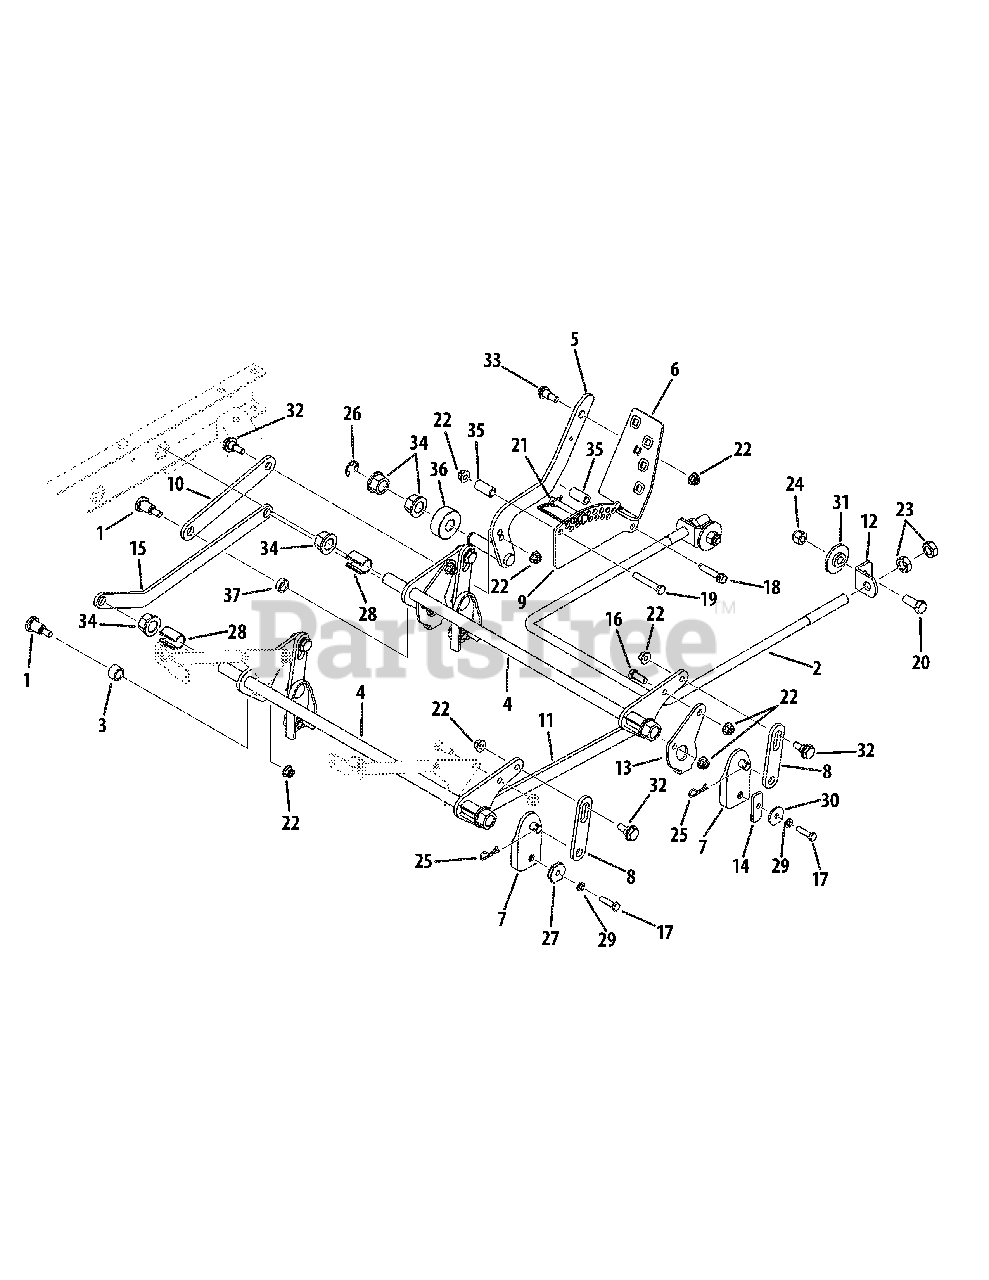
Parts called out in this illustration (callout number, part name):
1	Shoulder Screw, .625 x .830
3	Spacer, .632 x .877 x .548
5	Foot Lift Pivot Assembly
6	Lift Pedal Assembly
6	Lift Pedal Service Kit
6	Torsion Spring
6	Screw .50X.925
7	Deck Lift Adjustment Bracket
12	Front Hanger Rod Bracket Mount
13	Deck Up Stop Bracket
14	Deck Lift Square Spacer
15	Mid-Angled Link Plate
16	Hex Screw, 3.8-16 x 1.00
17	Hex Screw, 5.16-18 x 1.25
18	Hex Washer Screw, 3.8-16 x 1.875
19	Hex Screw, 3.8-16 x 2.25
20	Hex Screw, 1.2-13 x 1.25
21	Lock Pin, .375 x 2.25
22	Flange Lock Nut, 3.8-16
23	Jam Nut, 5.8-11
24	Hex Lock Nut, 1.2-13
25	Click Pin, .092 x 1.64
26	E-Type Ring, .750
27	Adjustable Deck Gear
28	Spacer, .791 x .950 x 1.35
29	Lock Washer, 5.16
30	Flat Washer, .330 x 1.25 x .120
31	Shoulder Spacer, .9790 x .2025
32	Shoulder Spacer, 3.8-16 x .562 x .360
33	Shoulder Screw, 3.8-16 x .50 x .50
34	Hex Flange Bearing, .752
35	Spacer, .375 x .625 x 1.290
36	Spacer, .760 x 2.000 x .790
37	Spacer, .632 x .877 x .281
